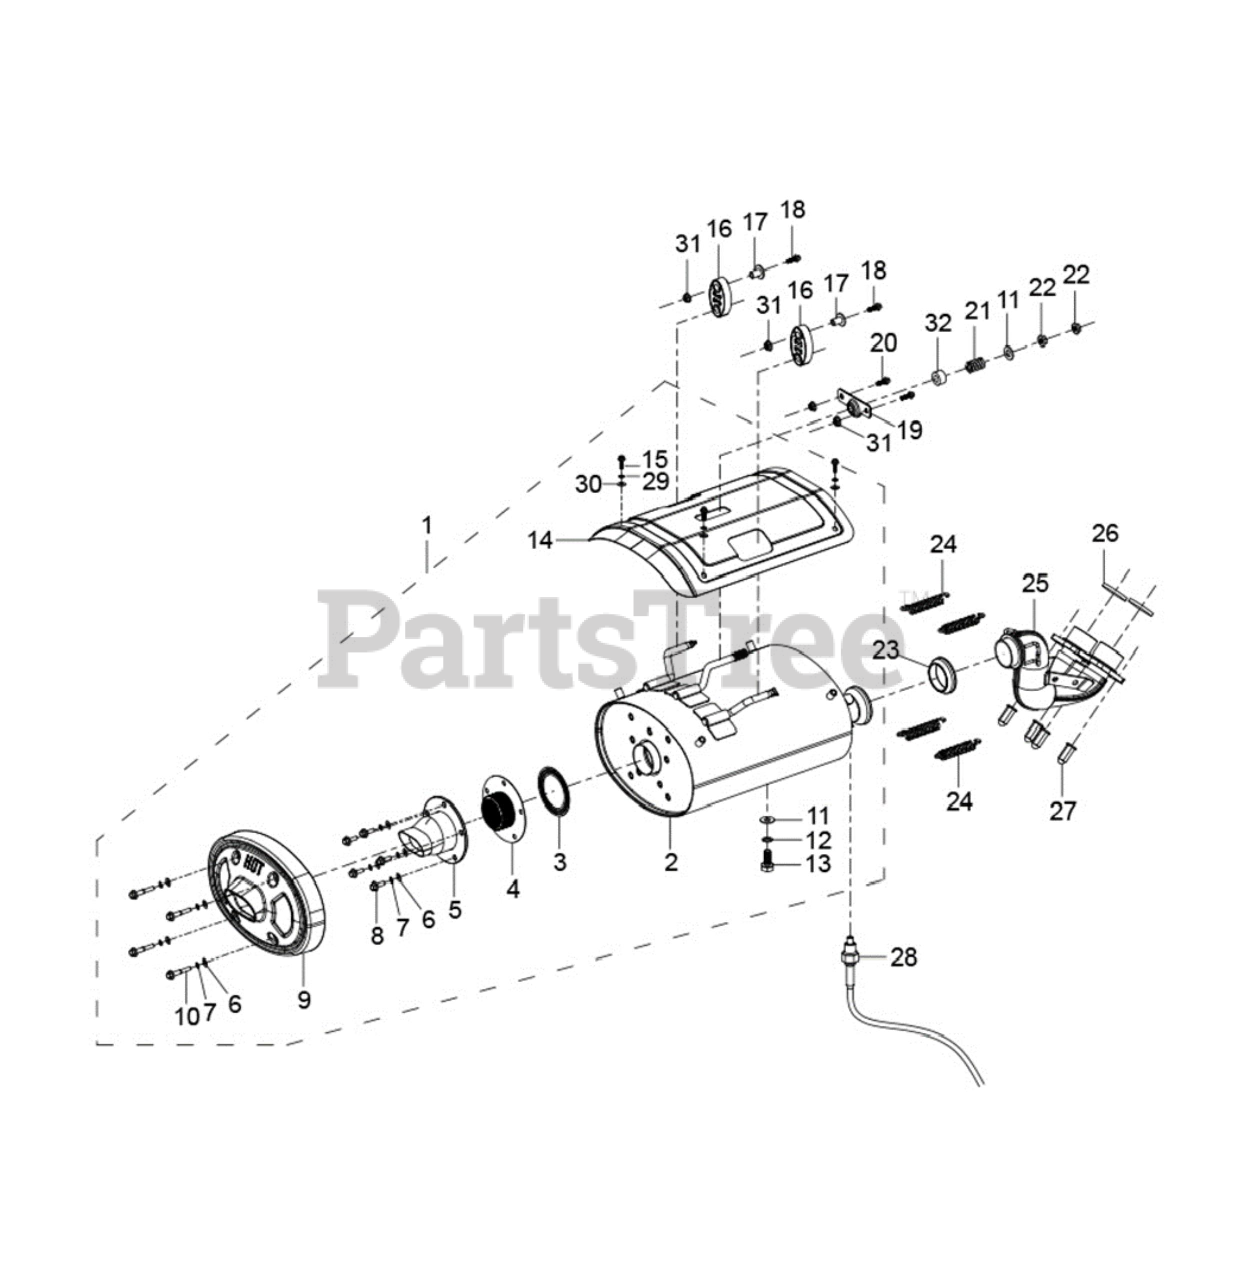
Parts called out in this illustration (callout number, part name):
1	MUFFLER ASSEMBLY
2	Muffler welding kit
3	HEAT PROTECTOR GASKET
4	SPARK ARRESTER
5	SPARK ARRESTOR COVER
6	WASHER - FLAT
7	WASHER - SPRING LOCK 8
8	Hexagon Flange BoltM6x20
9	MUFFLER CAP
10	BOLT HExAGON FLANGE HEAD M6x45
11	WASHER - FLAT 10x28x2
12	Spring Washer10
13	BOLT HExAGON FLANGE HEAD M10x1.25-20
14	MUFFLER HEAT PROTECTOR
15	BOLT HEx SOCKET M6x16
16	MUFFLER SHOCK PAD
18	Flange Bolt M6x25
19	MOUNTING PLATE
20	Hexagon Flange Bolt M6x16
21	PRESSURE SPRING P
22	HEXAGONAL NUT M10 X 1.25
23	DOMED WASHER
25	EXHAUST PIPE MANIFOLD
26	EXHAUST PIPE GASKET 33X42X6
28	OXYGEN SENSOR
29	WASHER - SPRING LOCK 8
30	WASHER - FLAT
31	HEXAGON FLANGE HEAD NUT M6
32	TUBE 10.5X20X7.5
